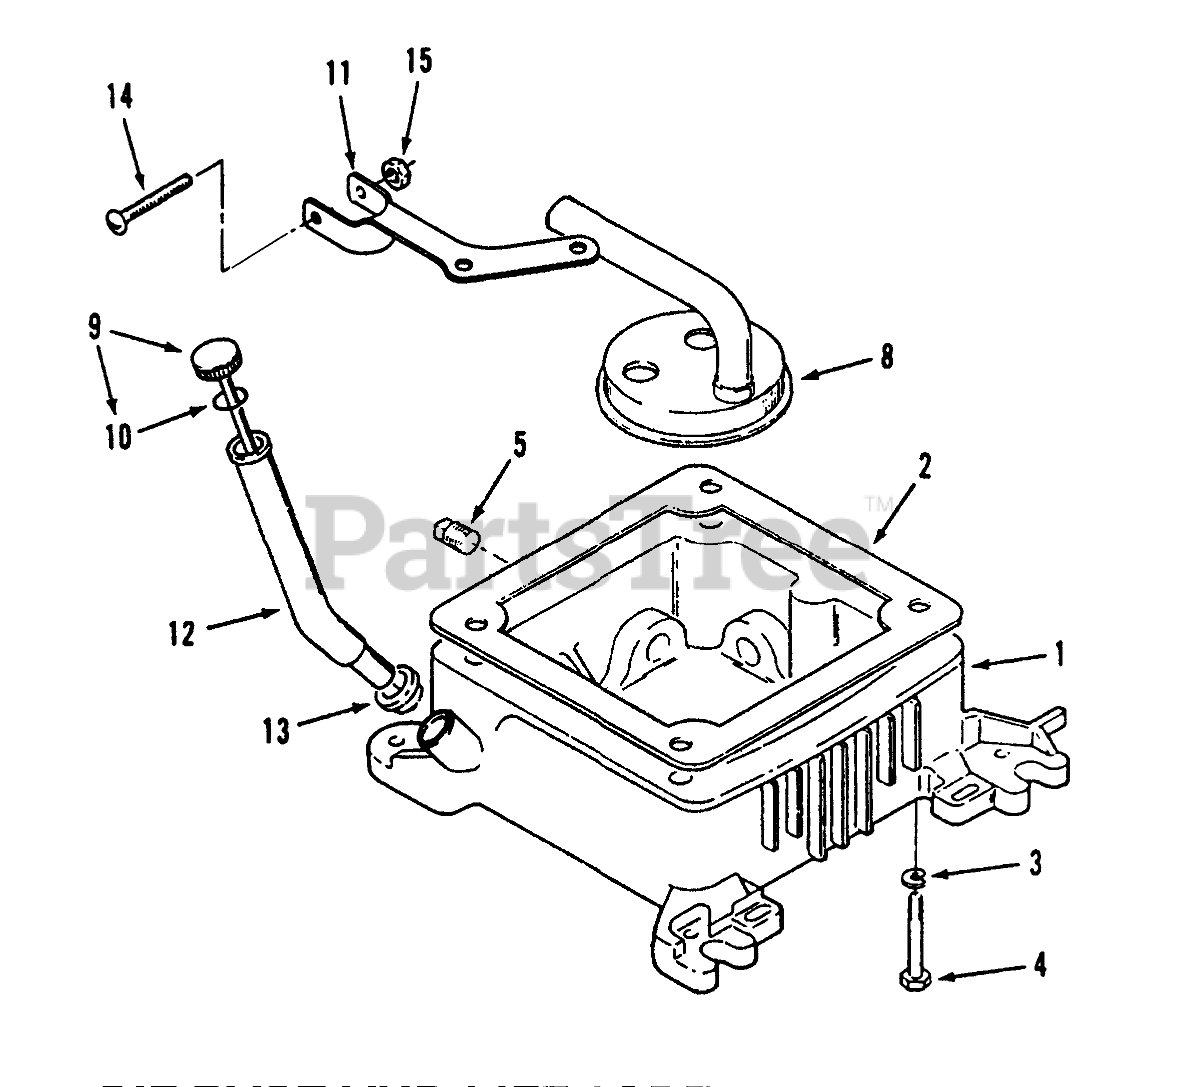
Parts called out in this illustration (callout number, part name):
1	Base-Oil (Incl. All Plugs & Plug Gasket)
2	GASKET
3	WASHER-FLAT
4	HHCS 3/8-16 X 3 3/4
5	PLUG - SQUARE HEAD
8	Cup-Oil Pump Intake
9	Cap-Oil Fill & Indicator (Incl. "O" Ring)
10	O-Ring
11	BRACKET-FILL TUBE
12	TUBE-OIL FILL
13	Seal
14	SCREW - PAN HEAD
15	NUT - SPEED
